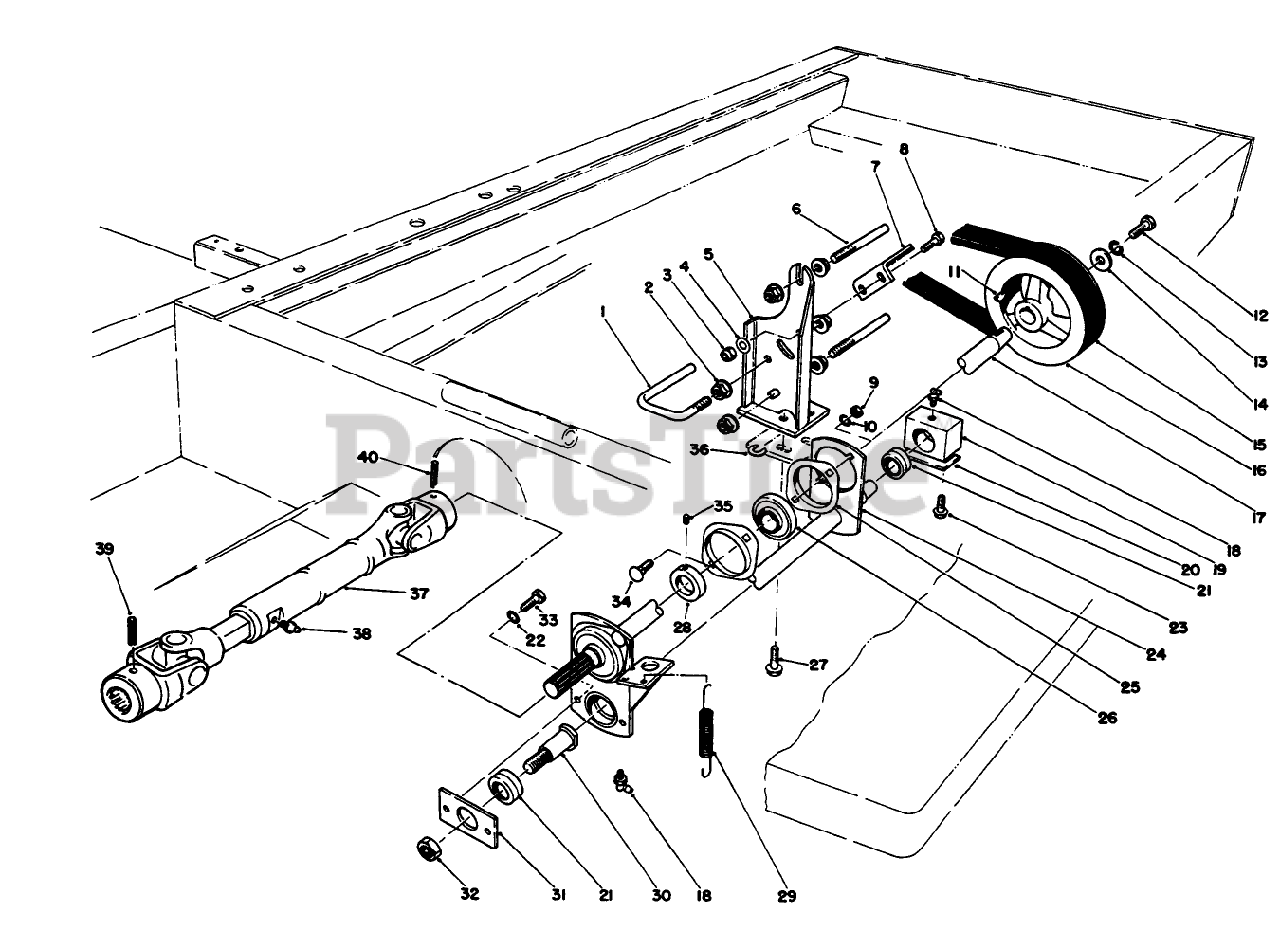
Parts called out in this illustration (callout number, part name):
1	LOWER BELT GUIDE
2	NUT-HHF, WHIZ
3	NUT-LOCK, NI
4	WASHER-PLAIN
5	Bracket-Brake
6	UPPER BELT GUIDE
7	PTO SUPT PAD ASM
8	SCREW-HH
9	NUT-HEX
10	WASHER-LOCK
11	KEY-WOODRUFF
12	SCREW-HH
13	WASHER-LOCK
14	WASHER-FLAT
15	V-BELT
16	Pulley-PTO
17	PTO SHAFT
18	FITTING-GREASE, 90 DEG
19	BEARING HUB PP
20	PTO SHIM BLOCK
21	BEARING
22	WASHER-LOCK
23	SCREW-HHF
24	ARM WA - ENGAGE R
25	FLANGE
26	Bearing w/Collar (Incl. Ref. #28 & 35)
27	SCREW-HHF
28	COLLAR-LOCK, BEARING
29	TENSION PTO SPRING R
30	BEARING STUD
31	BRG RETAINER
32	NUT-LOCK, NI
33	SCREW-HH
34	SCREW-CARR
35	SCREW-SET, HSH
36	SPECIAL WASHER
37	UNIVERSAL JOINT
38	FITTING-GREASE
39	PIN-ROLL
40	ROLL PIN
